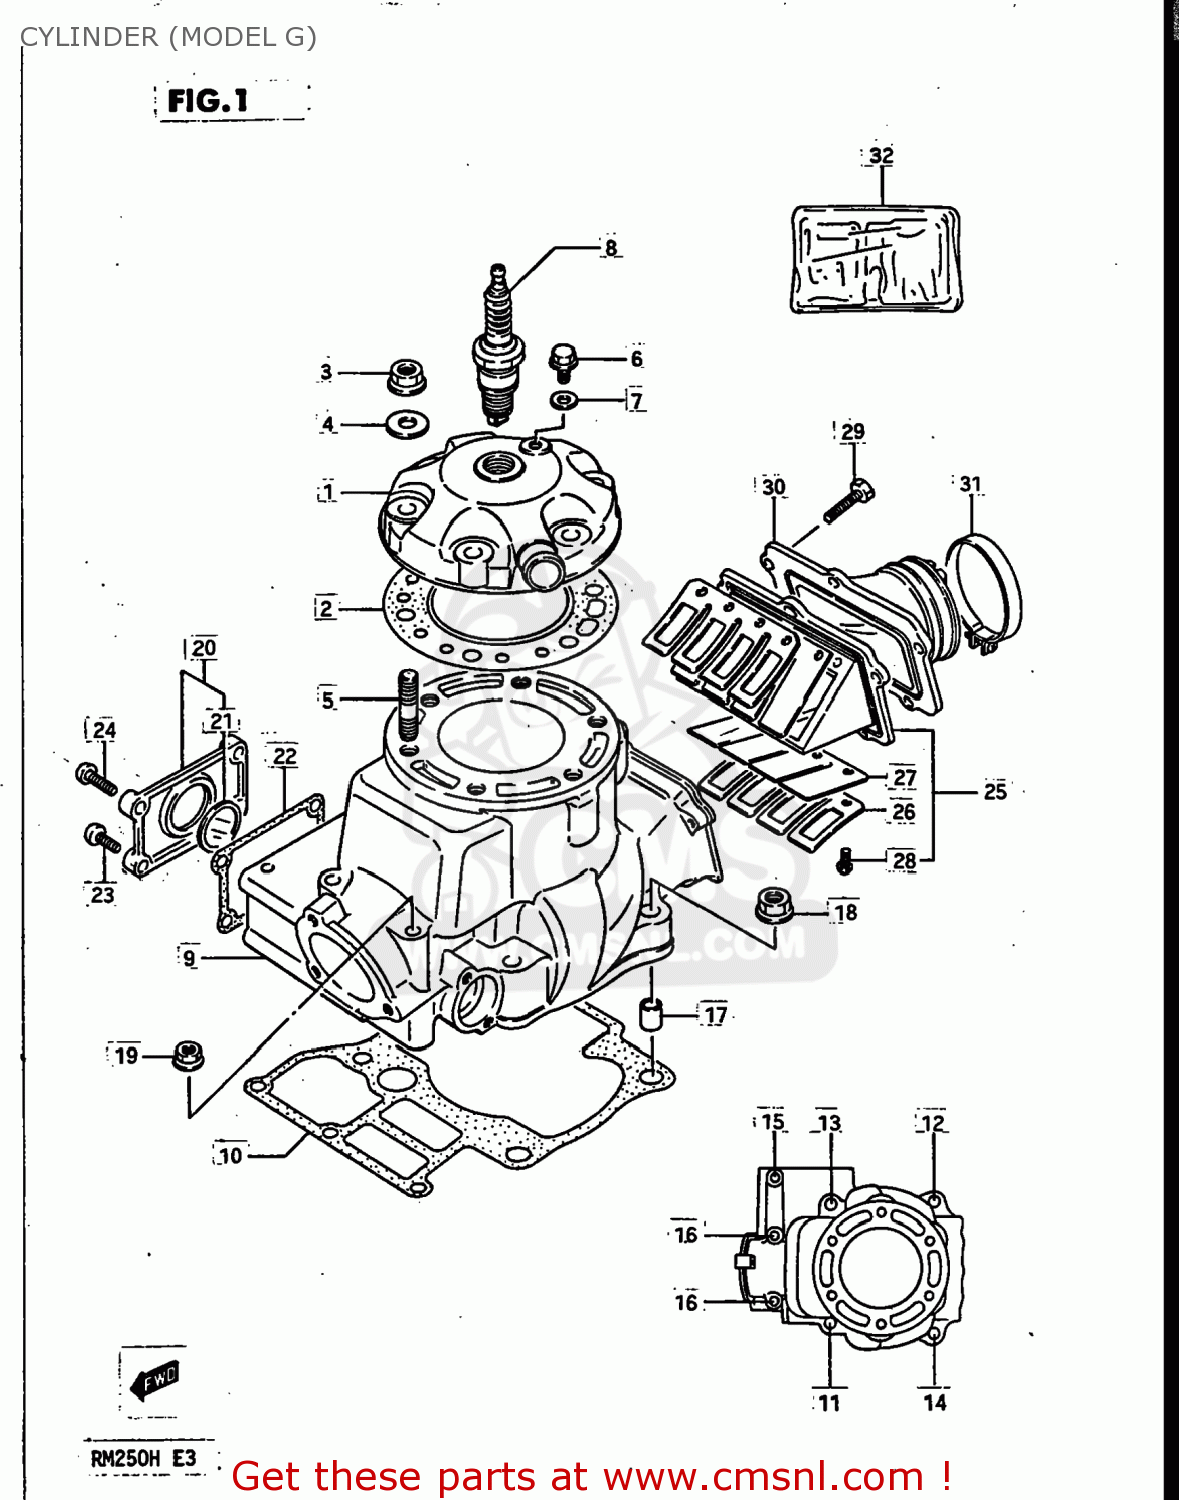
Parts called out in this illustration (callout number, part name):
1	HEAD,CYLINDER
2	GASKET,CYLINDER HEAD (MCA)
3	NUT
4	WASHER
5	BOLT,STUD
6	UNION
7	GASKET(6.2X11X1).2 (NAS)
8	PLUG,SPARK(NGK B-8EN)
9	CYLINDER
10	GASKET,CYLINDER (NAS)
11	BOLT,STUD
12	BOLT,STUD
13	BOLT,STUD
14	BOLT,STUD
15	STUD BOLT
16	STUD BOLT
17	PIN
18	NUT
19	NUT
20	COVER,CYLINDER
21	LENS,CYLINDER COVER
22	GASKET,CYLINDER COVER (MCA)
23	SCREW
24	SCREW
25	VALVE ASSEMBLY,REED
26	STOPPER,REED VALVE
27	VALVE,REED
28	SCREW
29	BOLT
30	PIPE,INTAKE
31	CLAMP
32	GASKET SET (MCA)
